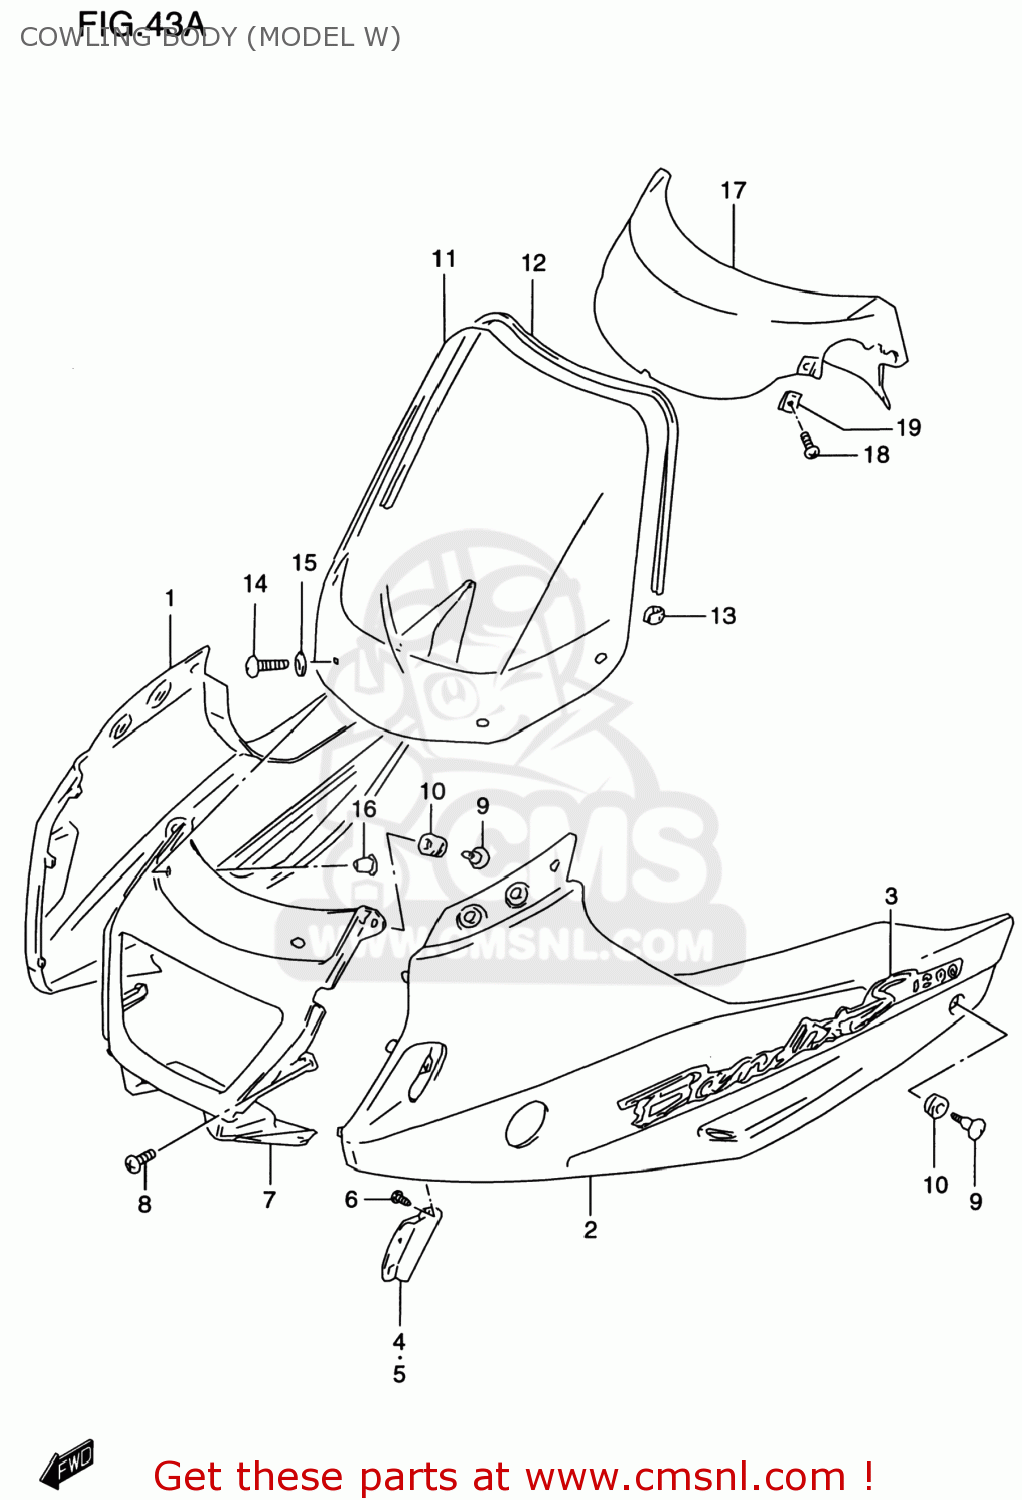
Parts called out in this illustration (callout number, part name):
1	COWLING ASSY,SIDE,R
2	COWLING ASSY,SIDE,L
3	EMBLEM,COWLING SIDE
4	COVER,COWLING INNER,R
5	COVER,COWLING INNER,L
6	SCREW 5X10
7	COWLING ASSY,CTR
8	SCREW
9	SCREW(6X20)
10	CUSHION
11	WINDSCREEN SET
12	MOLDING WINDSCREEN
13	CLIP,WINDSCREEN MOLDING
14	SCREW(5X14)
15	WASHER
16	NUT
17	PANEL,INNER
18	SCREW
19	NUT
